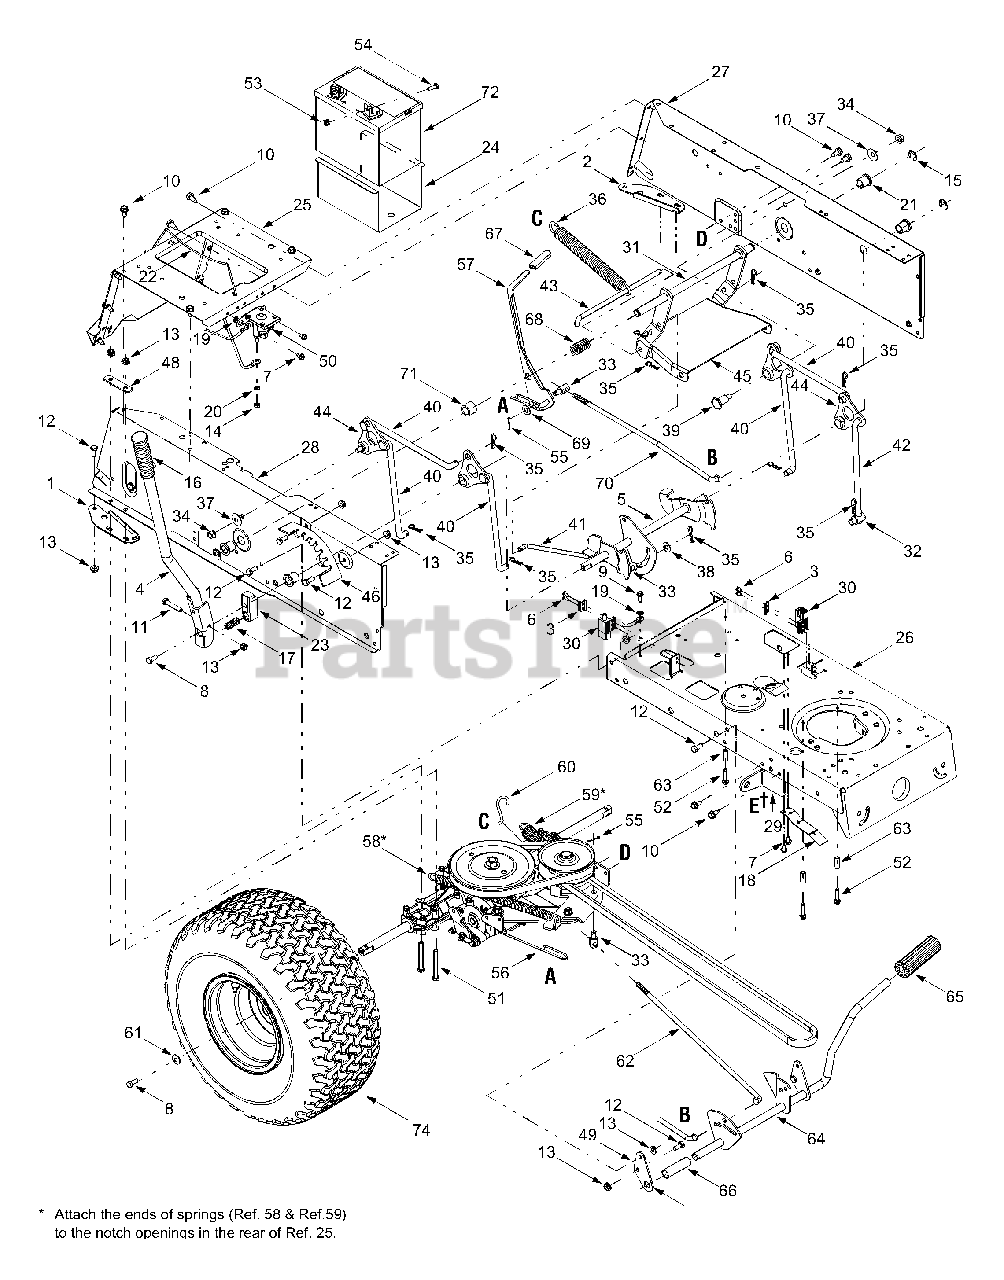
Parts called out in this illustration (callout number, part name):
6	Self-tapping Screw, #10-16 x .5
7	Self-tapping Screw, 1/4-20 x .5
8	Hex Cap Screw, 5/16-24 x .75
9	Self-tapping Screw, 1/4-20 x .75
10	Self-tapping Screw, 5/16-12 x .75
11	Hex Cap Screw, 5/16-18 x 1.75
12	Hex Screw, 5/16-18 x .75
13	Hex Lock Nut, 5/16-18
14	Hex Nut, 1/4-20
15	E-Ring, .625 Dia Shaft
16	Handle Grip
17	Compression Spring, .55 x 1.37
18	Switch Actuator Spring
19	External Lock Washer, 1/4
20	Lock Washer, 1/4
21	Flange Bearing, .632 ID
22	Battery Hold-down Rod
23	Lift Shaft Connector
33	Ferrule, 3/8-24 x .375
34	Hex Lock Nut, 3/8-16
35	Internal Cotter Pin, .080 x 1.56
36	Extension Spring, 1.07 x 9.52
37	Bell Washer, .389 x 1.12 x .030
38	Flat Washer, .385 x .87 x .060
39	Shoulder Bolt, .625 x .217
40	Deck Hanger Link
41	Deck Disengagement Rod
42	Deck Hanger Link
43	Rear Stabilizer Rod
44	Lift Link
46	Deck Lift Index Bracket
51	Hex Cap Screw, 5/16-18 x 2.75
52	Self-tapping Screw, 1/4-20 x 1.25
53	Hex Sems Nut, 1/4-20
54	Hex Screw,1/4-20 x .75
56	Extension Spring, .59 x 12.38
57	Speed Select Lever
58	Extension Spring, .73 x 12.54
59	Extension Spring, 1.15 x 7.90
60	Brake Return Spring
61	Bell Washer, .34 x .872 x .060
62	Variable Speed Control Rod
63	Spacer, .260 x .372 x 1.030
66	Spacer, .640 x .76 x 2.63
67	Shift Handle Grip
68	Compression Spring, .89 x 1.75
69	Flat Washer, .406 x .875 x .059
70	Speed Control Rod
71	Spacer, .640 x 1.0 x .78
72	Battery, 190 CCA
73	Flange Lock Nut, 1/4-20
